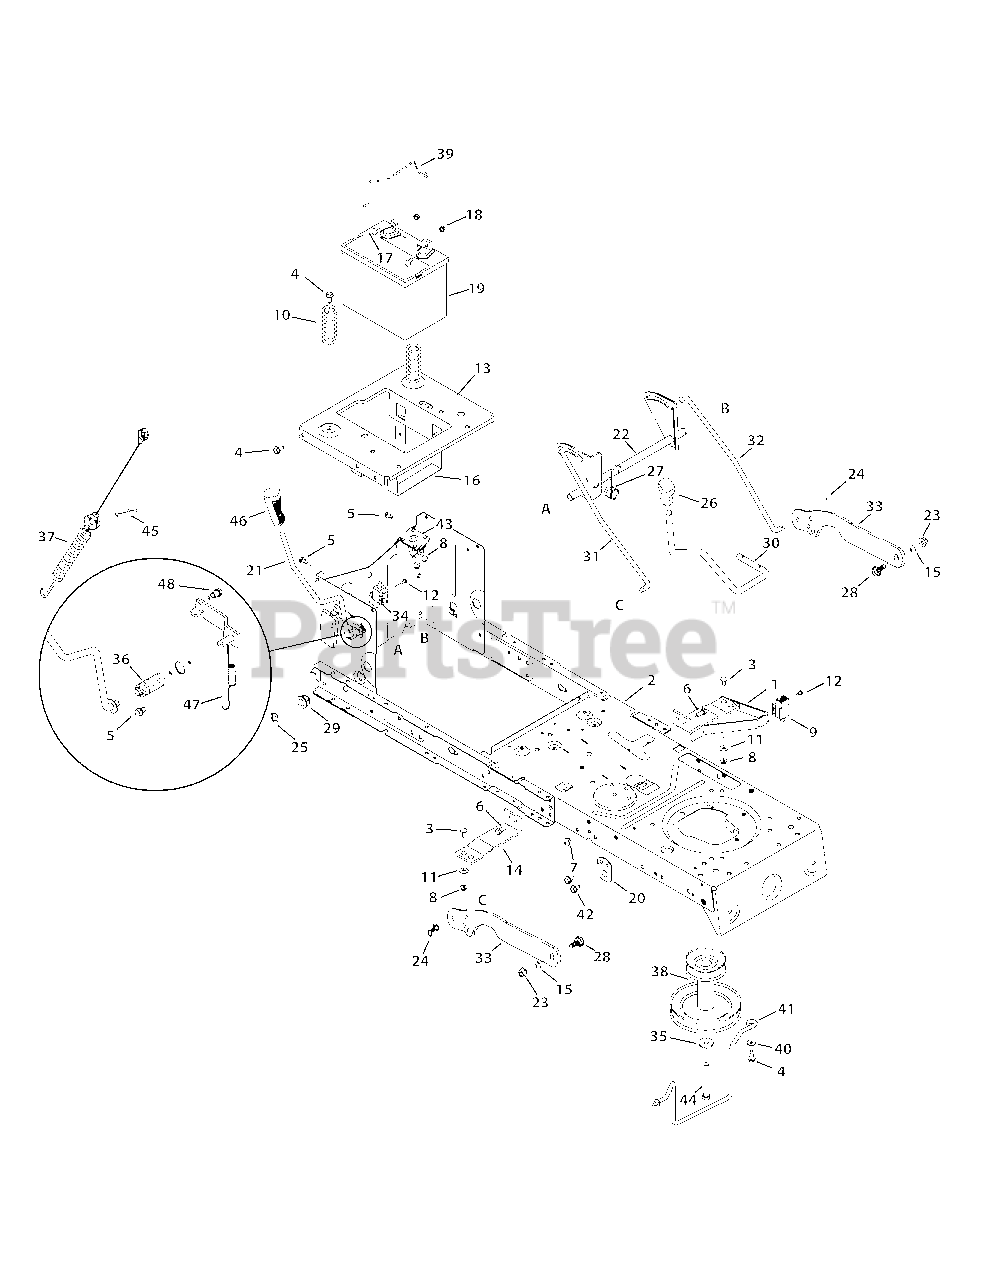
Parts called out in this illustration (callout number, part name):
1	Support Bracket
2	Frame Assembly
3	Screw Carriage, 1/4-20 x .75
4	Screw 5/16-18 x .750
5	Screw, 1/4-20 x .500
6	Hex Screw, 5/16-18 x .75
7	Flangelock Nut, 5/16-18
8	Flangelock Nut, 1/4-20
9	Screw Mount Interlock Switch
10	Compression Spacer, 1.314 x 2.55
11	Flat Washer, .28 x .74 x .063
12	Shoulder Spacer, 10-32 x .500
13	Seat Frame Bracket
14	Running Board Bracket
15	Flat Washer, .385 x .62 x .063
16	Battery Bracket
17	Hex Head Flange, 1/4-20 x .75
18	Sems Nut, 1/4-20
19	230 CCA Battery
20	Support Bracket
21	PTO Handle Assembly
22	Lift Assembly
23	Flangelock Nut, 3/8-16
24	Bow-tie Cotter Pin
26	Handle Grip, 5/8
27	Torsion Spring
28	Shoulder Bolt, 3/8-16 x .50 x .270
29	Hex Flange Bearing
30	Deck Lift Handle
31	Lift Rod, RH
32	Lift Rod, LH
34	Switch Interlock
35	Flat Washer, .450 x 1.250 x .164
36	PTO Bearing
37	Deck Engage Cable
38	Engine Pulley, 3.39 x 6.12
39	Battery Hold Down Rod
40	Flat Washer, .406 x .875 x .059
41	42" Belt Keeper
42	Screw, 5/16-18.0 x .625
43	12V Solenoid
44	Hex Screw, 7/16-20 x 3.25
45	Click Pin, .092 x 1.64
46	Handle Grip, 3/8
47	PTO Spring Extension
48	Shoulder Bolt, 1/4-28 x .342 x .335
